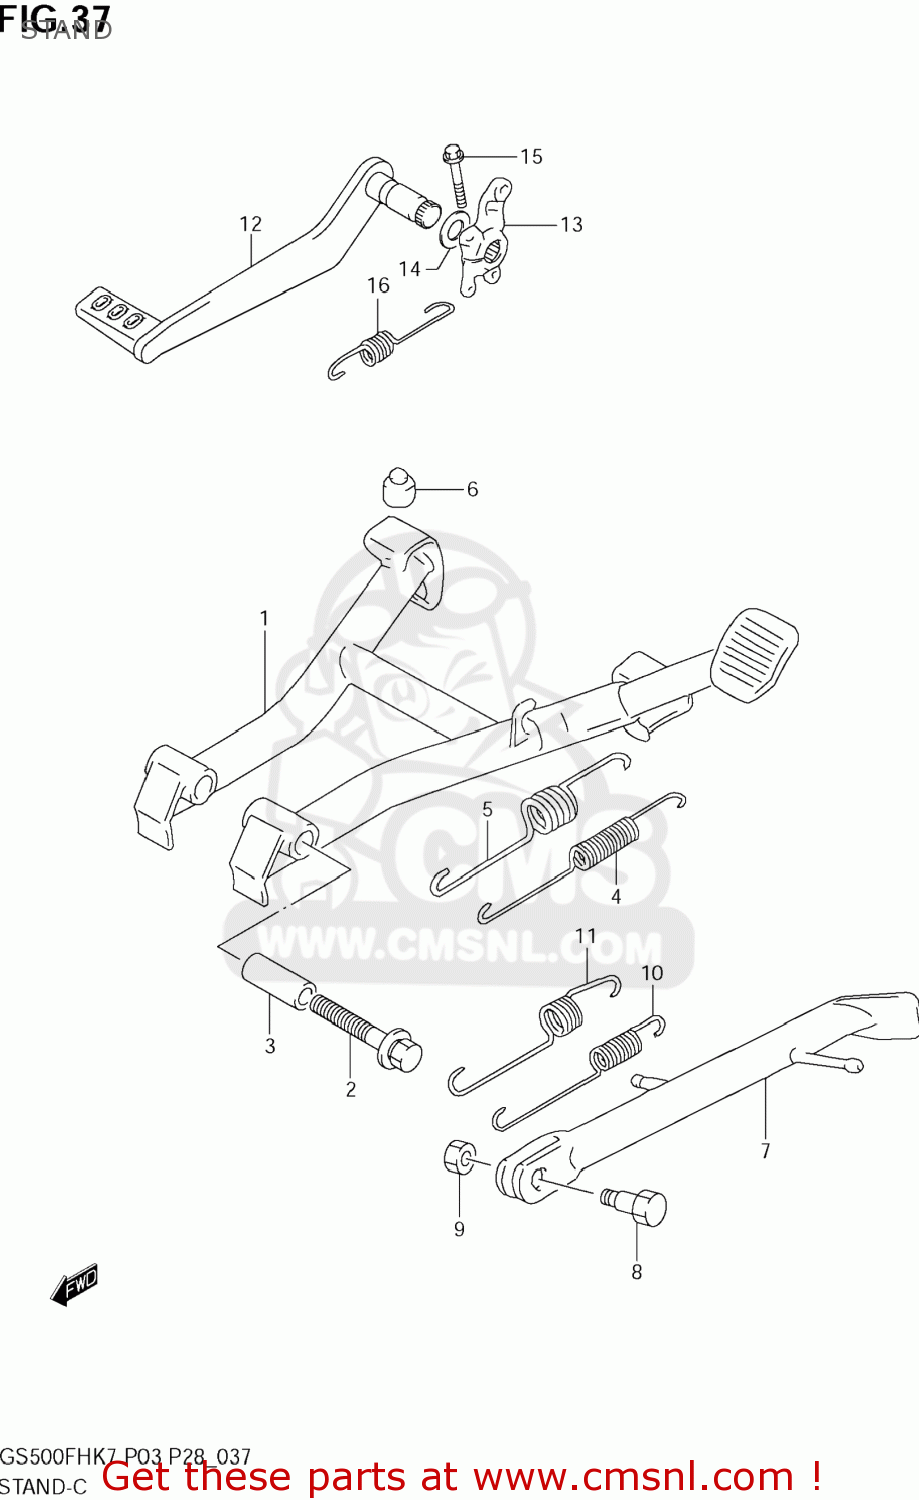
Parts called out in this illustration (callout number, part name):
1	STAND, CENTER
2	BOLT
3	SPACER(10X16X38.8)
4	SPRING
5	SPRING OUTER
6	CUSHION
7	STAND,PROP
8	BOLT(10X34)
9	NUT
10	SPRING
11	SPRING
12	PEDAL, BRAKE
13	ARM, BRAKE ROD
14	WASHER
15	BOLT
16	SPRING
